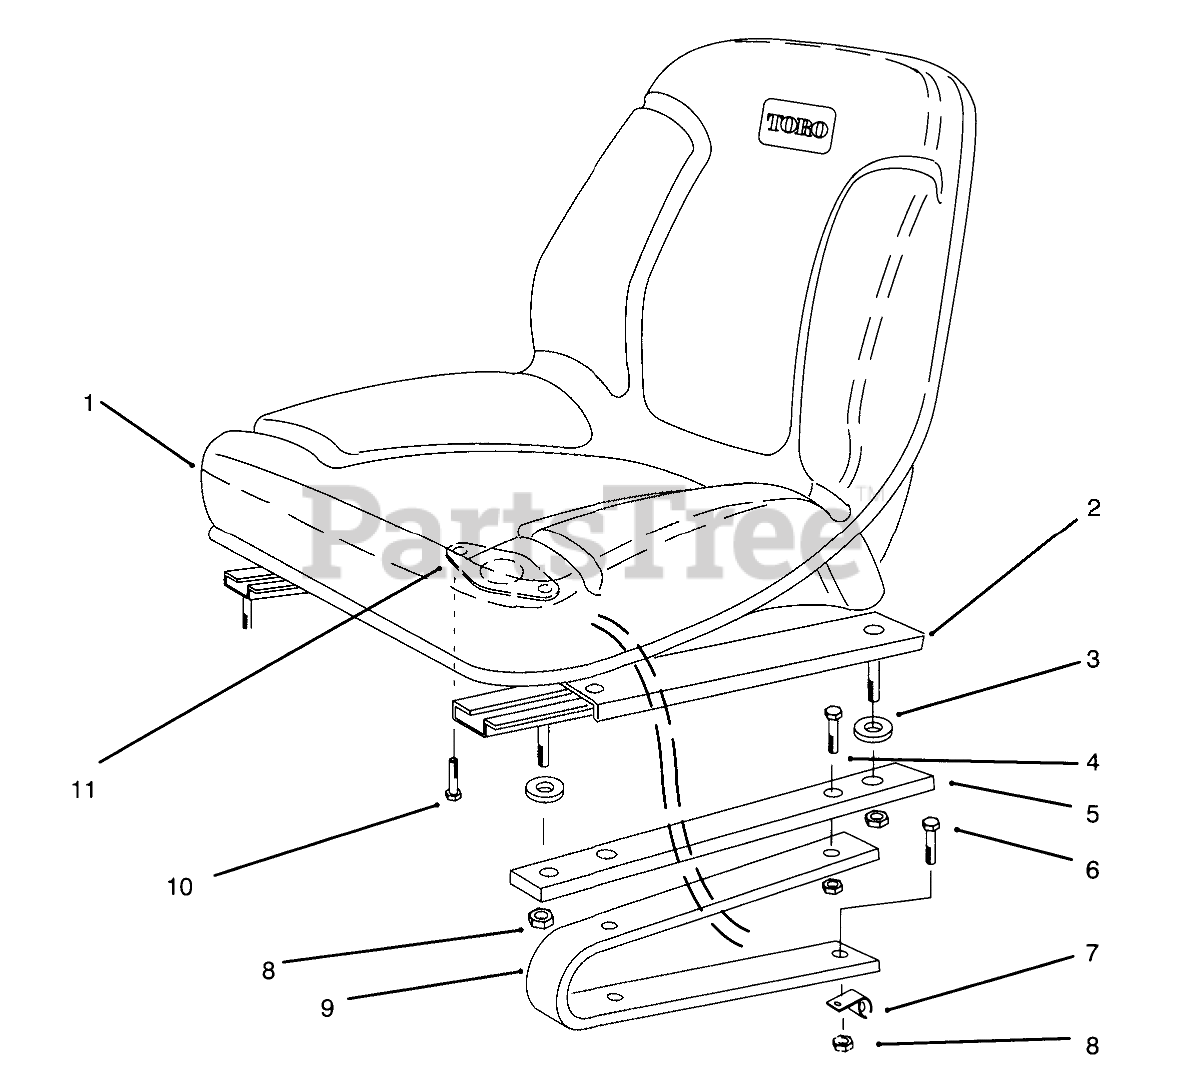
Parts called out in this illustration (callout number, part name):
1	SEAT ASM
2	ADJUSTER-SEAT, LH
3	SPACER-NYLON
4	SCREW-HH
5	Plate-Adapter, Seat
6	SCREW-HH
7	CLAMP-R
8	NUT-LOCK, NI
9	Seat Spring
10	SCREW-HH
11	SWITCH-SEAT
